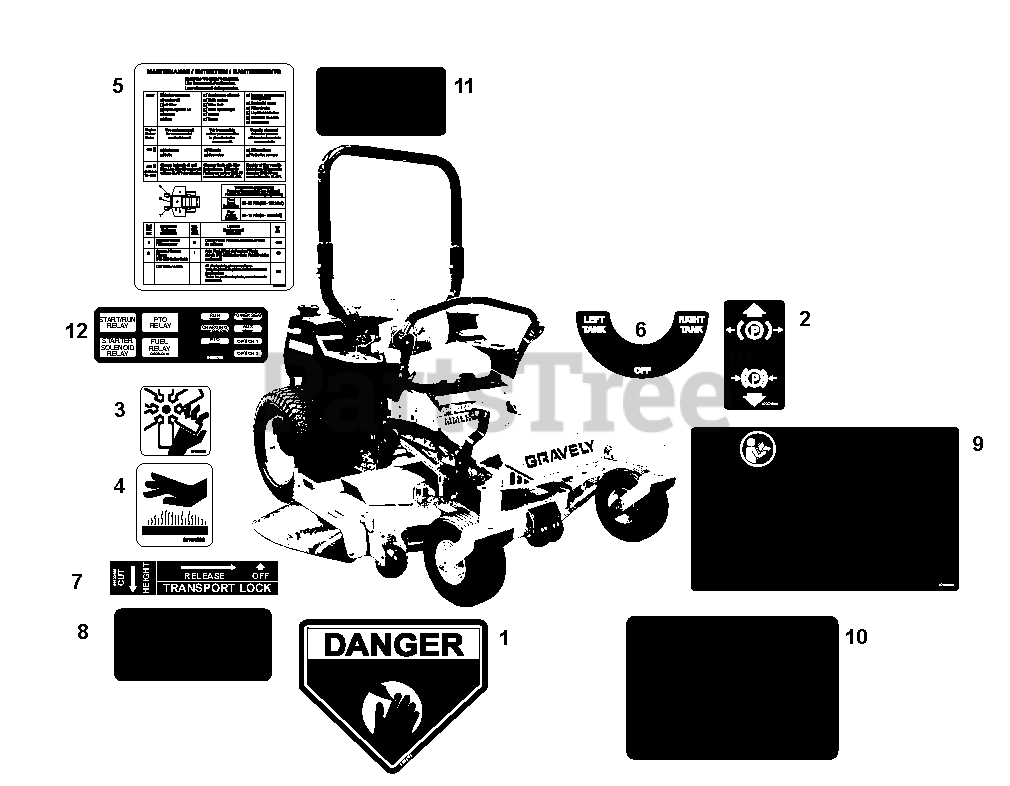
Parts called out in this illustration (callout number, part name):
1	Decal, Danger
2	Decal, Parking Brake Lever
3	Decal, Danger Fan
4	Decal, Hot Surface
5	Decal, Maintenance Instructions
6	Decal, Fuel Control Valve
7	Decal, Transport Lock
8	Decal, Deck Guarding Safety
9	Decal, Instruction
10	Decal, Mower Deck Safety
11	Decal, Safety Guarding
12	Decal, Fuse Box Layout
